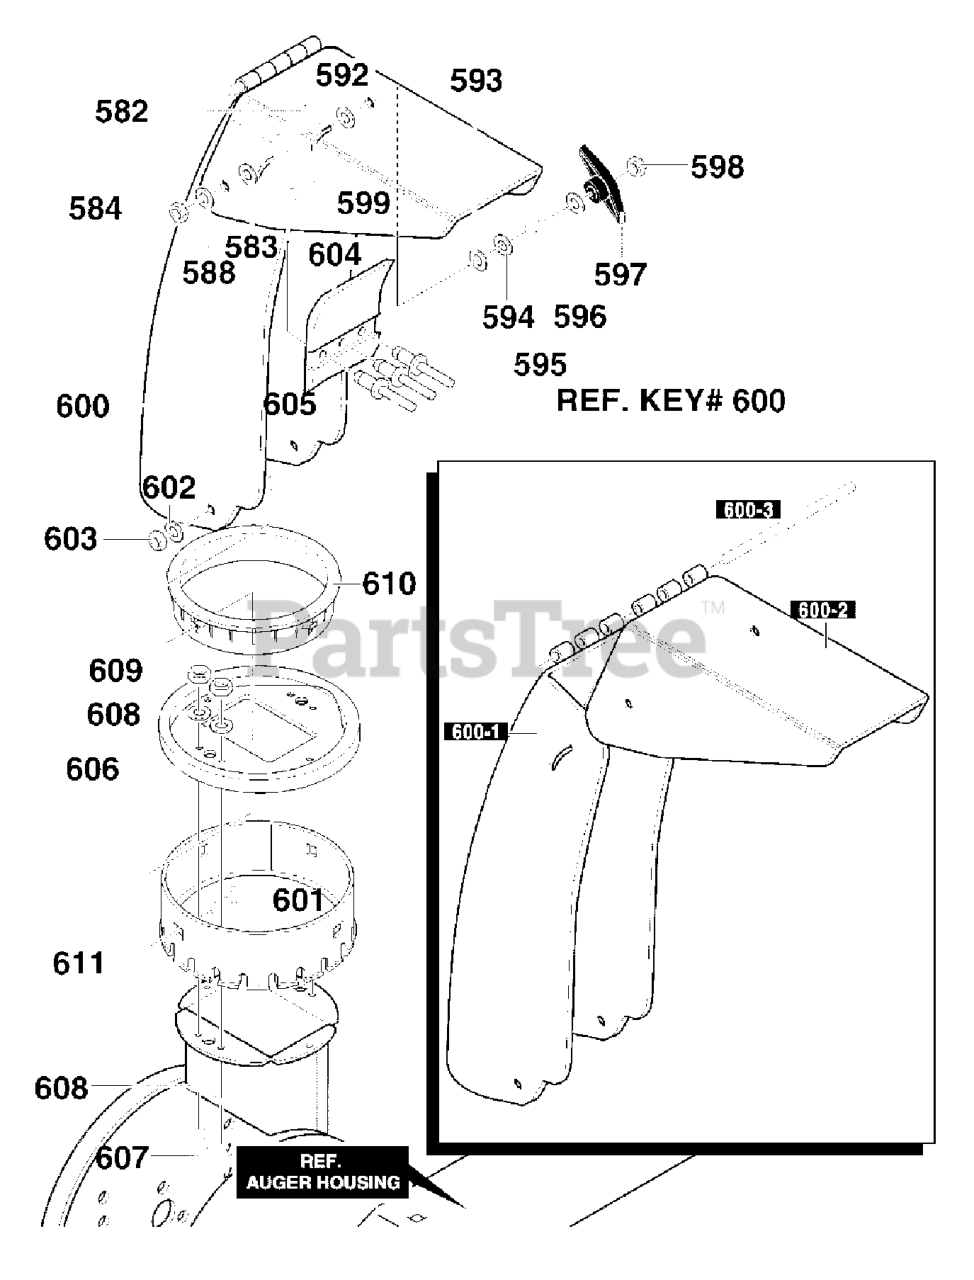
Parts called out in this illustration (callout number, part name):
582	BOLT, 5/16-18 X.75
583	WASHER , PLASTIC
584	NUT, 5/16-18
588	WASHER, PLASTIC
592	WASHER, PLASTIC
593	WASHER, PLASTIC
594	FLATWASHER .349X.69X.066
595	WASHER, SPLITLOCK
596	FLATWASHER .349X.69X.066
597	KNOB, T 2/BLADE W/NUT
598	NUT, 5/16-18 REGHEX
599	CARR. BOLT, 5/16-18X1.00
600-1	CHUTE, LOWER
600-2	CHUTE, UPPER
601	BOLT, 5/16-18 X1.00
602	WASHER, FLAT .349 X.69 X.066
603	NUT, 5/16-18 HEXNYL
604	FLAP, CHUTE
605	POP, RIVET
606	CHUTE COLLAR
607	SCREW, 1/4-20X.75
608	WASHER, FLAT .281X.63X.065
609	NUT, 1/4-20 HEX NYLOCK
610	RETAINER, RING INNER
611	RETAINER, RING OUTER
